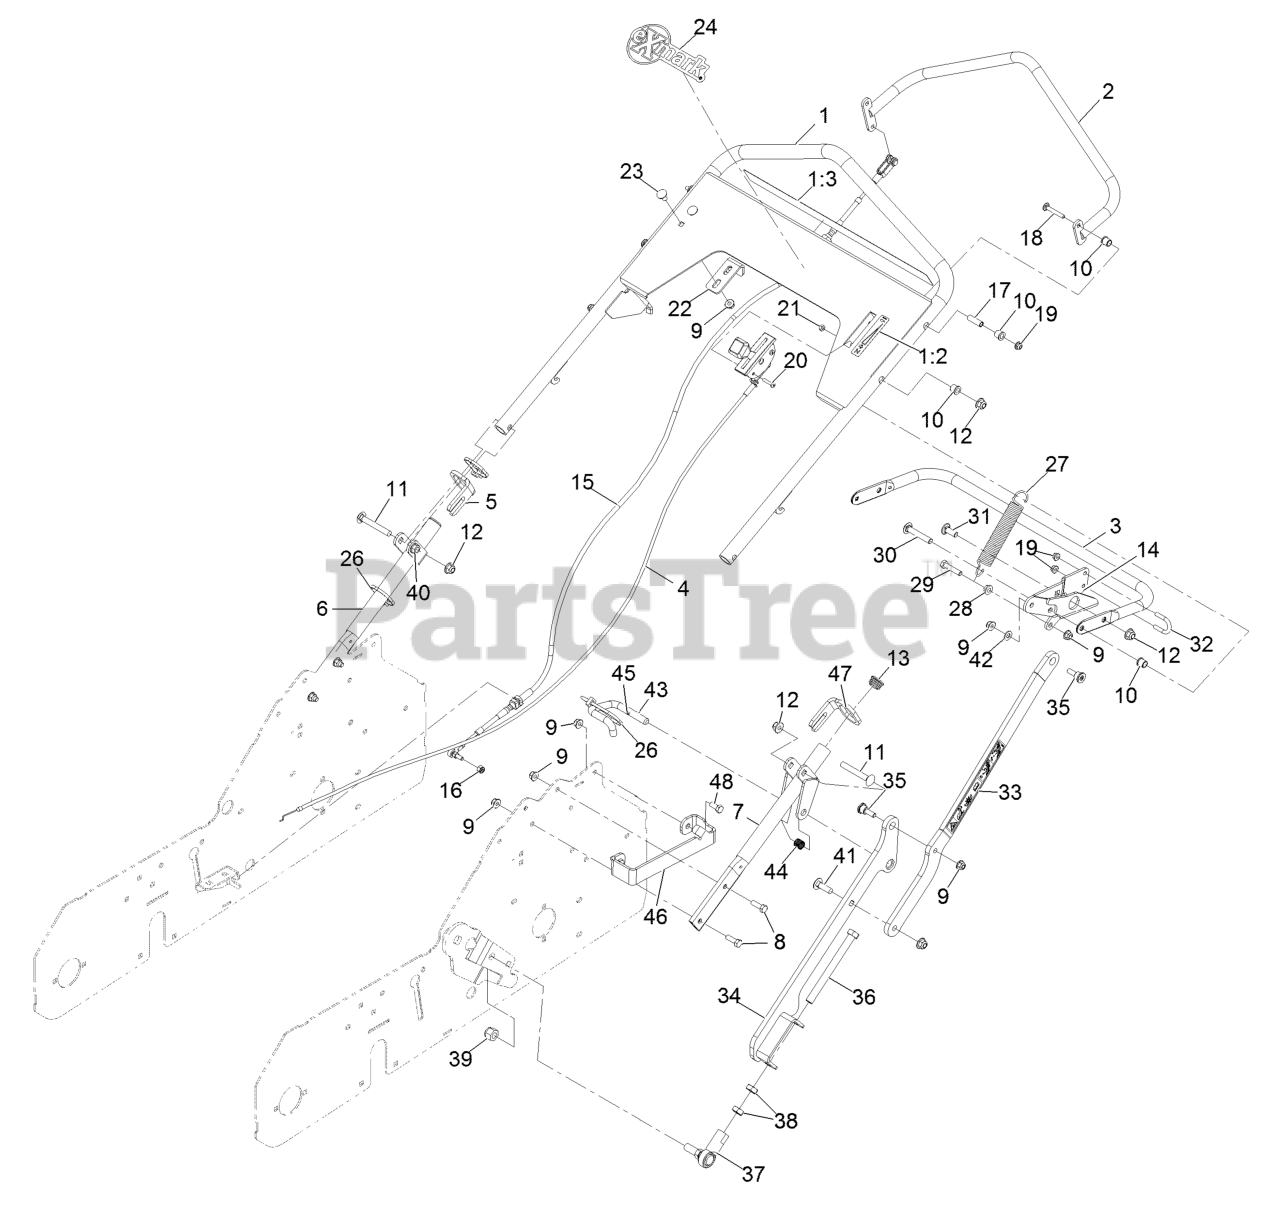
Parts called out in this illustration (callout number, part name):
1	HANDLE ASM
1:2	DECAL-THROTTLE, CHOKE
1:3	DECAL-AERATOR CONTROL PAN
2	TUBE-CONTROL
3	TUBE-HANDLE LIFT
4	CONTROL-THROTTLE
5	RING, HANDLE LOCK
6	HANDLE-LOWER
7	HANDLE-LOWER, LH
8	SCREW-HH
9	NUT-HF, NI
10	BEARING
11	SCREW-CARR
12	NUT-HF, NI
14	ARM-UPPER
16	NUT-LOCK
17	BUSHING-PIVOT
18	SCREW-CARR
20	SCREW-PPH
21	NUT-LOCK, NI
22	ANGLE-STOP
23	SCREW-CARR
24	DECAL,EXMARK LOGO
26	TIE-CABLE
27	SPRING-EXTENSION
29	SCREW-HH
30	BOLT-CARR, SHORT NECK
31	SCREW-CARR
33	ASM, UPPER LINK W/ DECAL
34	ARM-LOWER
35	BOLT-SHOULDER, GROOMER
36	SCREW, HH
37	END-ROD, RH THREAD
38	NUT-JAM
39	NUT-HEX
40	NUT-HHF, WHIZ
41	BOLT-CARR
42	WASHER-PLAIN
43	PIN-LATCH, TRANPORT
44	SPRING-COMPRESSION
45	PIN-SPRING
46	STRAP, STOP
47	RING, HANDLE LOCK
48	SCREW-HH
